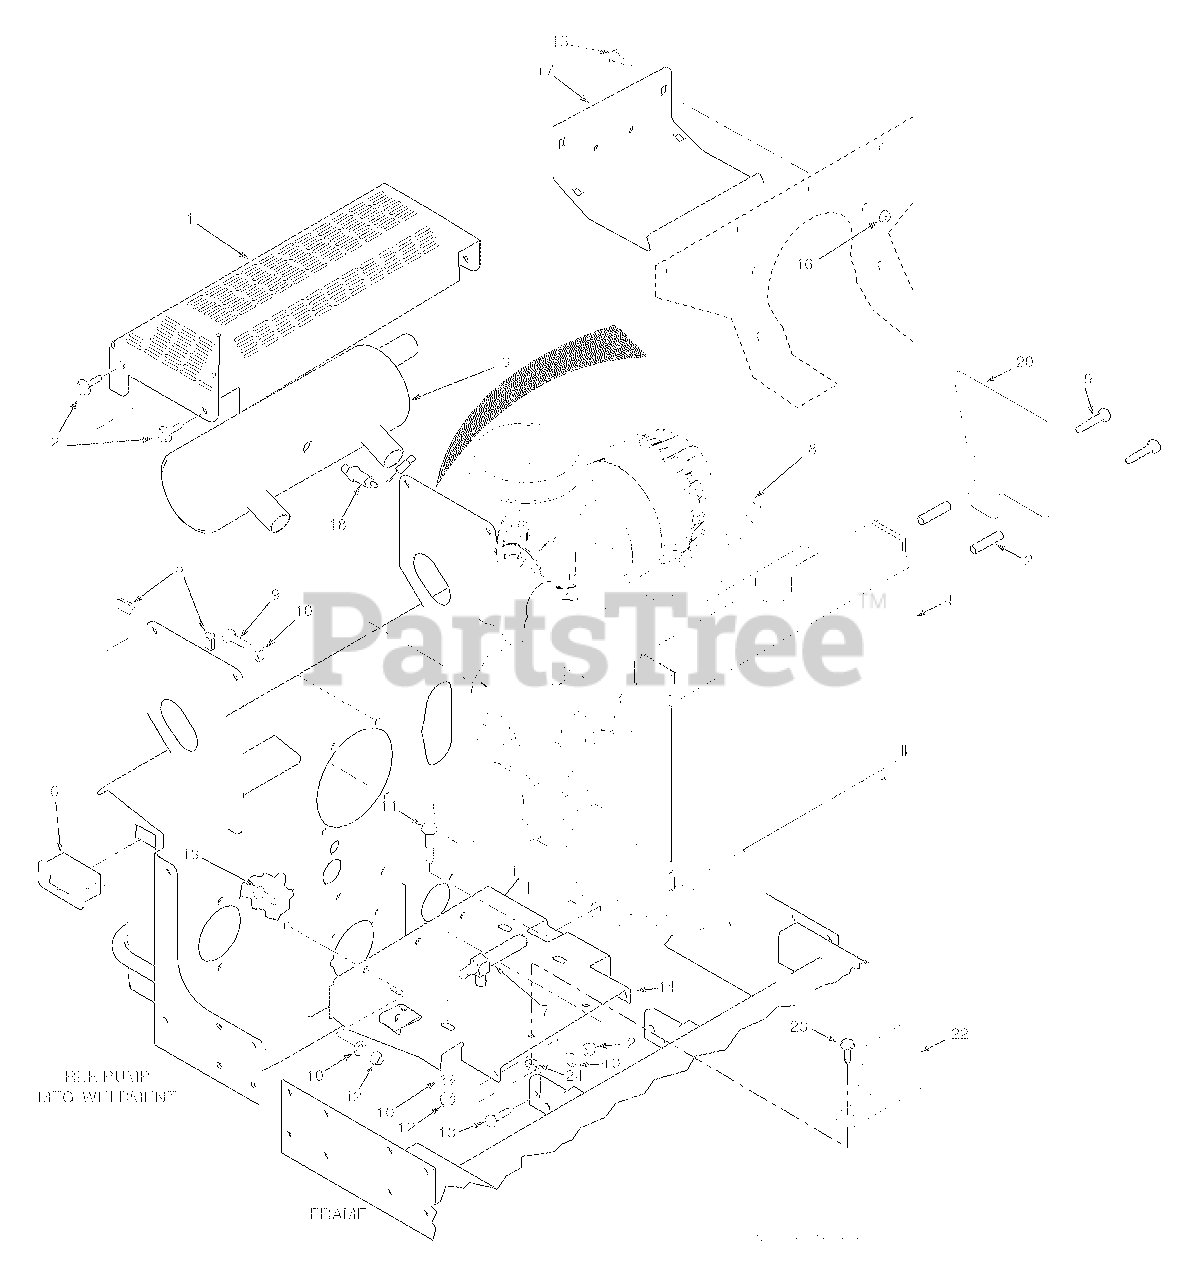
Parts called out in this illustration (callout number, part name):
1	Muffler Guard
2	Screw, Hex Serrated Flange 1/4-20 x 3/4"
3	Muffler
4	Screen Weldment, Radiator
5	U-Nut, 1/4-20
6	Hour Meter
7	Oil Drain Extension
8	Engine, Kohler 31HP-EFI Aegis
9	Bolt, Hex Head 3/8-16 x 1"
10	Lockwasher, 3/8" Spring
11	Bolt, Hex Head 3/8-16 x 1-3/4"
12	Nut, Hex Elastic Stop 3/8-16
13	Bolt, Hex Head 3/8-16 x 1-1/4"
14	Plate, Engine Mounting
15	Bolt, Carriage 5/16-18 x 3/4"
16	Nut, Hex Serrated Flange 5/16-18
17	Rear Cover
18	o2 Sensor
19	Bolt, Hex Head M6-1.0 X 90mm
20	Mounting Bracket, ECU Kohler EFI
21	Spacer, ECU Mounting
22	Mounting Bracket, Fuel Pump Kohler EFI
23	Bolt, Hex Head 1/4-20 x 3/4"
24	Nut, Serrated Flange 1/4-20
